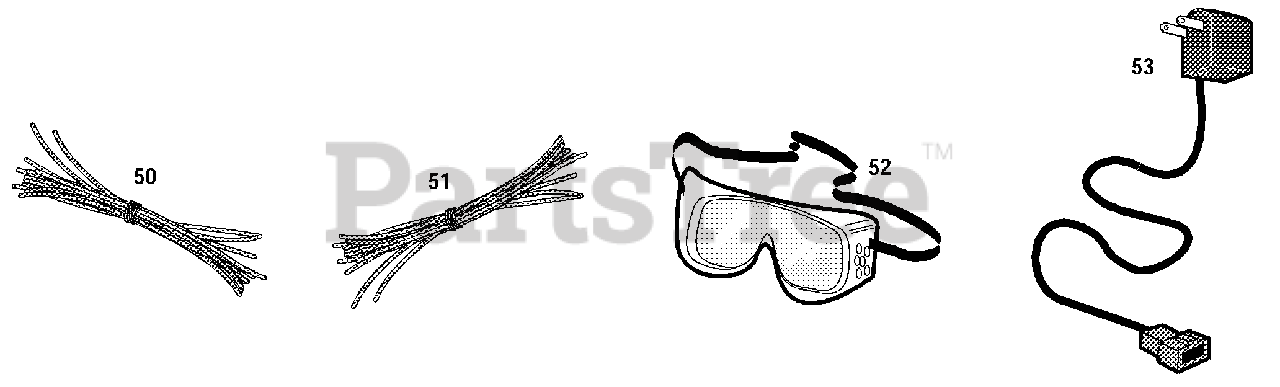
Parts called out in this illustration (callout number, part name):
50	Trimmer String Kit, .155"
51	Trimmer String Kit, .130"
52	Safety Goggles
53	Battery Charger (electric start units)
